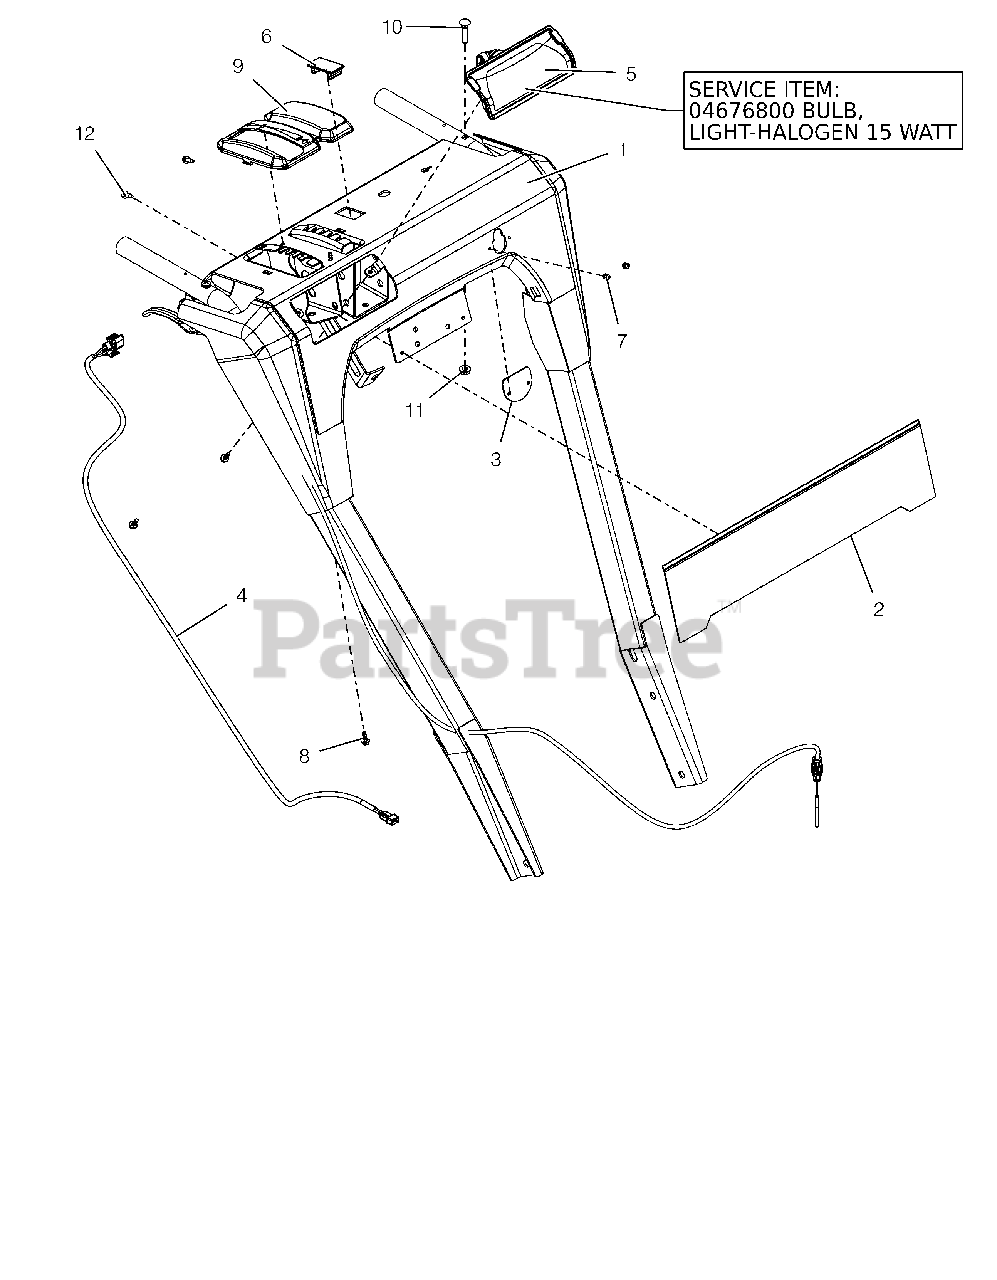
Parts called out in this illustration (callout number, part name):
1	PANEL, DASH - W/CTR DECAL
2	WLDMT, BRAND PLATE
3	COVER, DASH BRKT, BRUSH
4	HARNESS, LIGHT - DELUXE
5	HEADLIGHT ASY, HOLO 15W 2 SHOT
5	BULB, LIGHT-HALOGEN 15 WATT
6	PLUG,DASH PANEL
7	RVT-POP #43 .125X.313 STL ZINC
8	SCR-TAP #10X.50 BOSS INDHXHD
9	BEZEL, SHIFT - FRICTION BRUSH
10	BLT-RDHDXLSQNK.25-20X1.25 G5ZC
11	NUT-LK-CTR-FLG .25-20 YWZC
12	@SCR-TAP 10-24X.50 HWH TR YWZC
